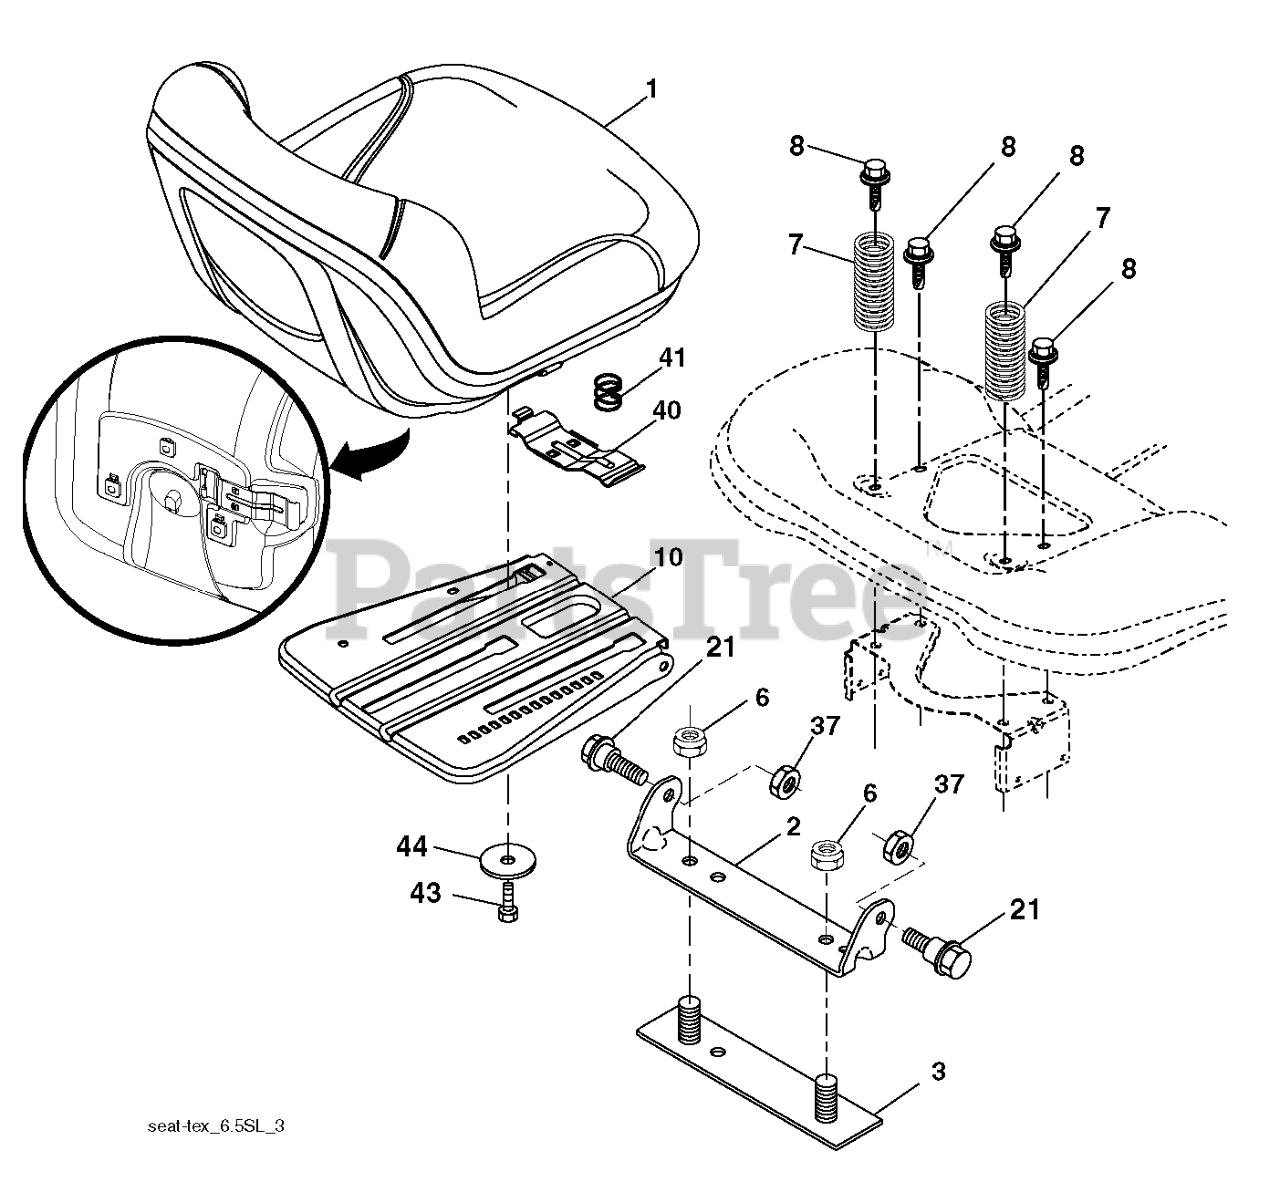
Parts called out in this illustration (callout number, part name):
1	RP SEAT, TH150, GREY, MILSCO
2	BRKT.PIVOT.FENDER
3	STRAP
6	NUT
7	SPRING COMPRESSION
8	BOLT.5/16-18UNCX3/4 W/SEMS.BLK
10	PAN.ASM.SEAT.3PT
21	BOLT.SHOULDER.5/16-18
37	NUT.71038.31-18.HEX.NYLOCK
40	HANDLE.SLIDE.SEAT.TEX.BLACK
41	SPRING.LATCH.SEAT.TEX
44	WASHER 13/32 X 2-3/8 X 12GA
